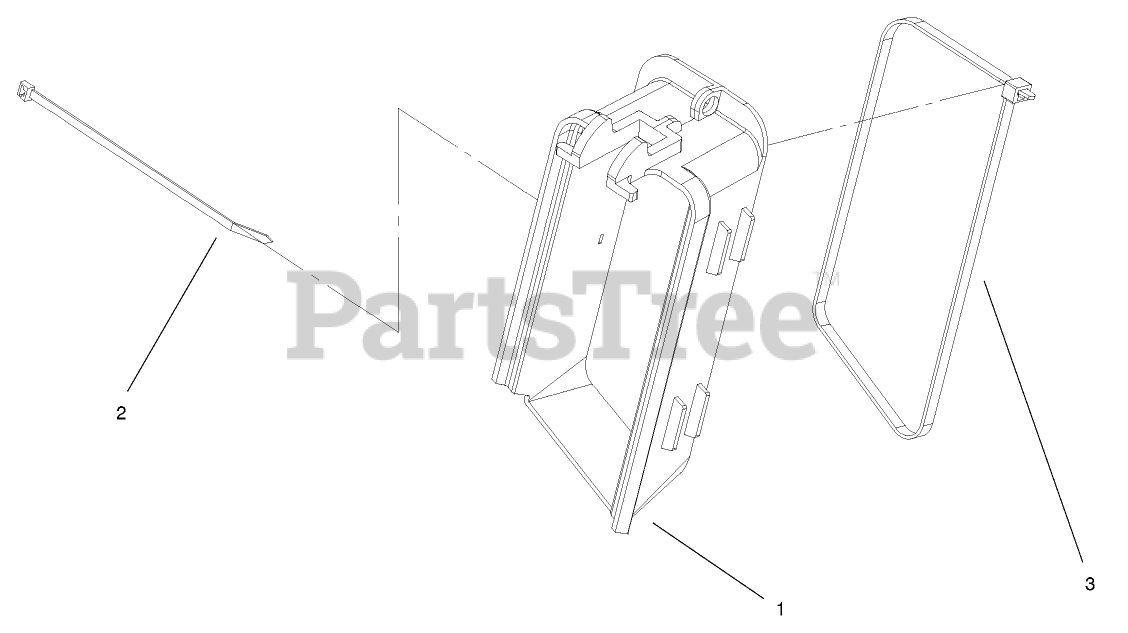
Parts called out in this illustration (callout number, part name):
1	Chute-Bag,Inlet
2	TIE-CABLE
3	STRAP-TIE
